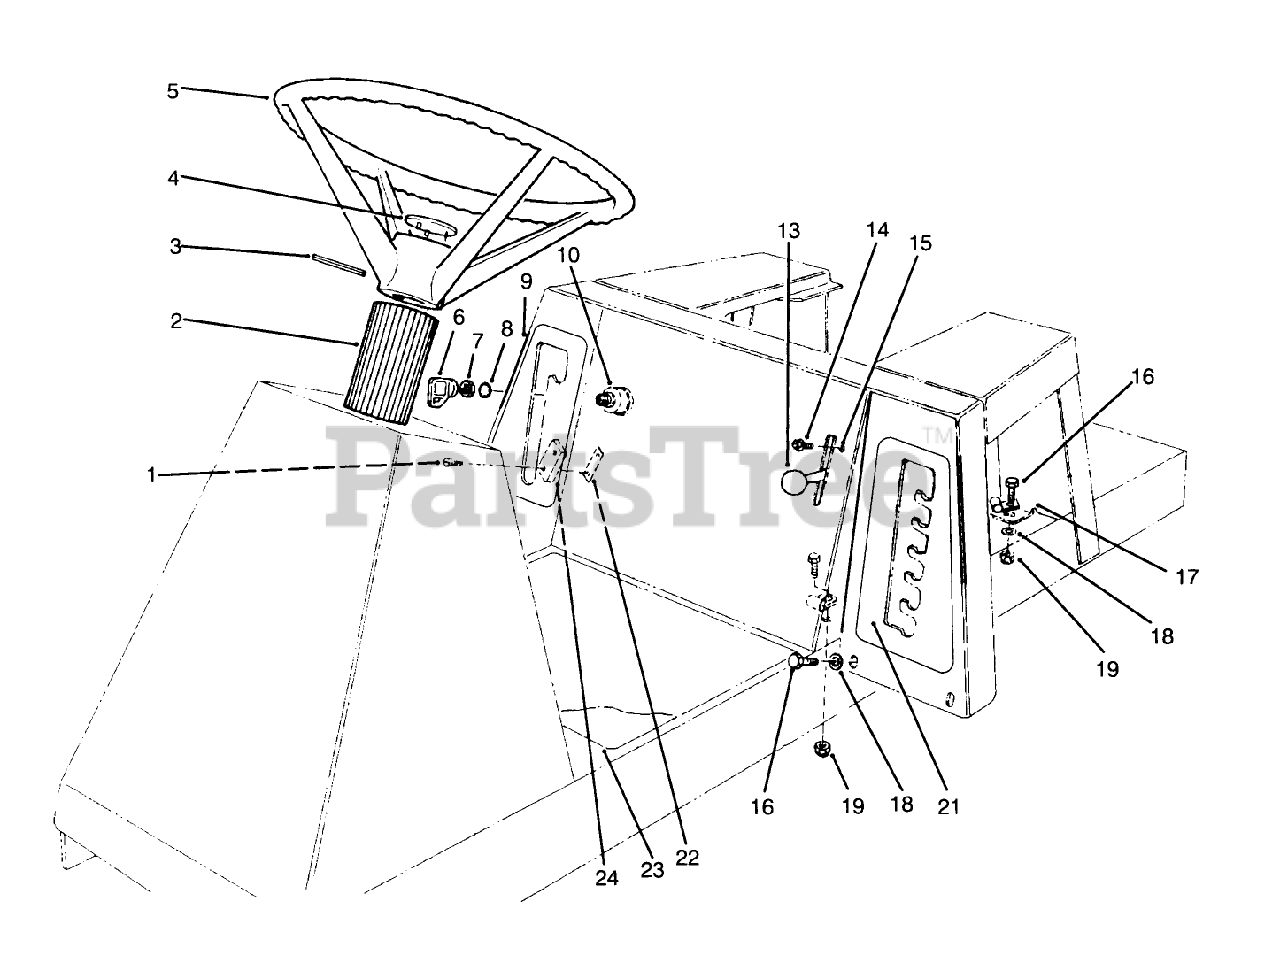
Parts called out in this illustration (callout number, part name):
2	COVER-STEERING SHAFT
3	PIN-ROLL
4	INSERT - STEERING WHEEL, WH EMBLEM
5	STEERING WHEEL ASM
6	KEY-IGNITION
7	NUT-HH
8	WASHER-LOCK
9	DECAL - DECK ENGAGE
10	SWITCH-STARTER
13	KNOB-CONTROL
14	SCREW-HWHTF
16	SCREW-HH
17	CLAMP
18	WASHER-PLAIN
19	NUT-LOCK, NI
21	DECAL - HOC
22	NUT-SPEED
24	SWITCH-MICRO
